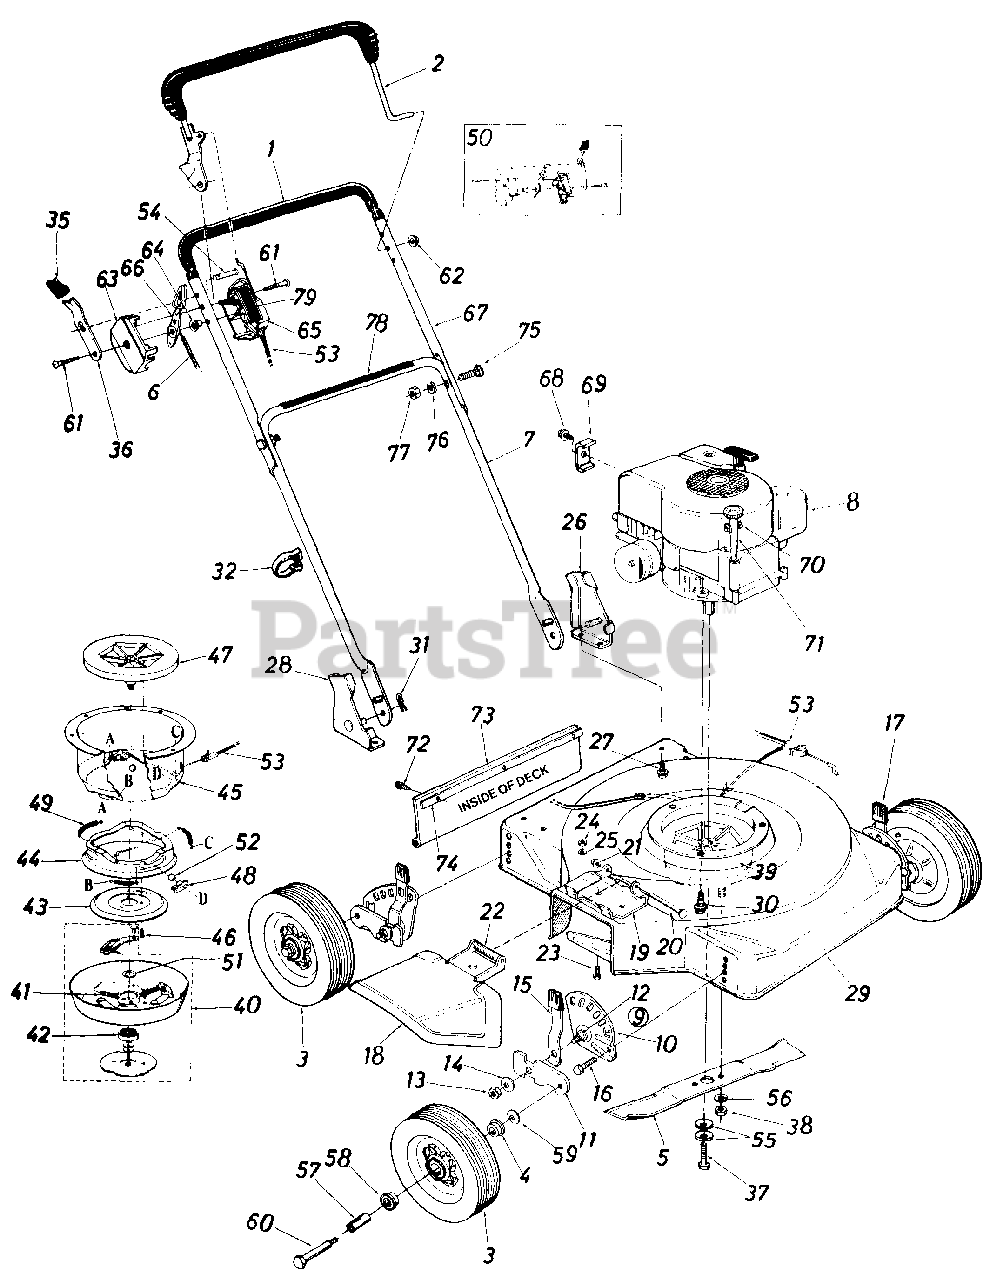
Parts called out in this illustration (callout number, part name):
2	Control Handle Ass'y-R.H.
3	Wheel Ass'y. Comp. 8.0 x 1.75
4	Ball Bearing 3/8" I.D.
5	20" Blade
6	Throttle Control Wire 39.0"-Red
7	Lower Handle
8	Engine
9	Height Adjuster Ass'y.-R.H.
10	Index Plate Ass'y.-L.H.
11	Pivot Bar
12	Shoulder Bolt
13	Hex Ins. L-Nut 3/8-24 Thd.
14	Bell-Wash. .400" I.D. x 1.13" O.D.
15	Spring Lever w/Knob
16	Hex Sems Bolt 3/8-16 x .62" Lg.
17	Height Adjuster Ass'y.-L.H.
18	Chute Deflector Ass'y. Comp.
19	Adapter Plate
20	Pivot Pin
21	Push Nut 1/4" Rod
22	Torsion Spring
23	Hex Bolt 1/4-20 x .50" Lg.
24	Hex Nut 1/4-20 Thd.
25	L-Wash. 1/4" I.D.
26	Handle Mount Brkt. Ass'y. - L.H.
27	Hex Wash. Hd. B-Tap. Scr. 5/16-18 x .50" Lg.
28	Handle Mount Brkt. Ass'y. - R.H.
29	20" Deck Ass'y.
31	Intern. Cot. Pin 5/16" Dia.
32	Cable Tie
35	Spring Lever Knob
36	Lockout Spring
37	Hex Bolt 3/8-24 x 2.00" Lg. (Grade 8)
38	Hex Nut 3/8-24 Thd. (Grade 8)
39	Blade Brake Clutch Comp.
40	Clutch Blade Housing Ass'y.
41	Compression Spring .35" O.D. x 2.00" Lg.
42	Ball Brg. .669 I.D. x 1.574 O.D.
43	Clutching Cone
44	Brake Cup Cone
45	Clutch Housing
46	Hex Tap L-Scr. 1/4-20 x .75" Lg.
47	Fan Adapter
48	Ball Block
49	Extension Spring .35" O.D. x 1.75" Lg.
50	Kit - Control Housing Comp.
51	Fl-Wash. .690" I.D. x 1.060 O.D.
52	Steel Ball .500" Dia.
53	Clutch Cable - 46.0"
54	Lock Pin .314" Dia. x 1.70"
55	Bell-Wash. .400" I.D. x .88" O.D.
56	L-Wash. 3/8" I.D.
58	Ball Bearing 1/2" I.D.
59	Bell-Wash. .400" I.D. x .88" O.D.
60	Axle Bolt
61	Truss Mach. Scr. #12 x 1.50"
62	Cap Speed Nut 5/16" Rod
63	Control Panel Half
64	Control Disc Pin
65	Clutch Panel Half
66	Throttle Control Lever
67	Upper Handle
68	Hex AB-Tap Scr. #8 x .38" Lg.
69	Casing Clamp
70	Hex Wash. Hd. "AB" Tap Scr. #8 x .50" Lg.
71	Short Ext. Oil Fill
72	Hex Wash. Hd. "AB" Tap Scr. 1/4 x .62" Lg.
73	Rear Flap Ass'y.
74	Retainer Strip
75	Curved Carriage Bolt 5/16-18 x 1.38" Lg.
76	L-Wash. 5/16" I.D.
77	Hex Nut 5/16-18 Thd.
78	Instruction Label - Handle
79	Control Label - Throttle
